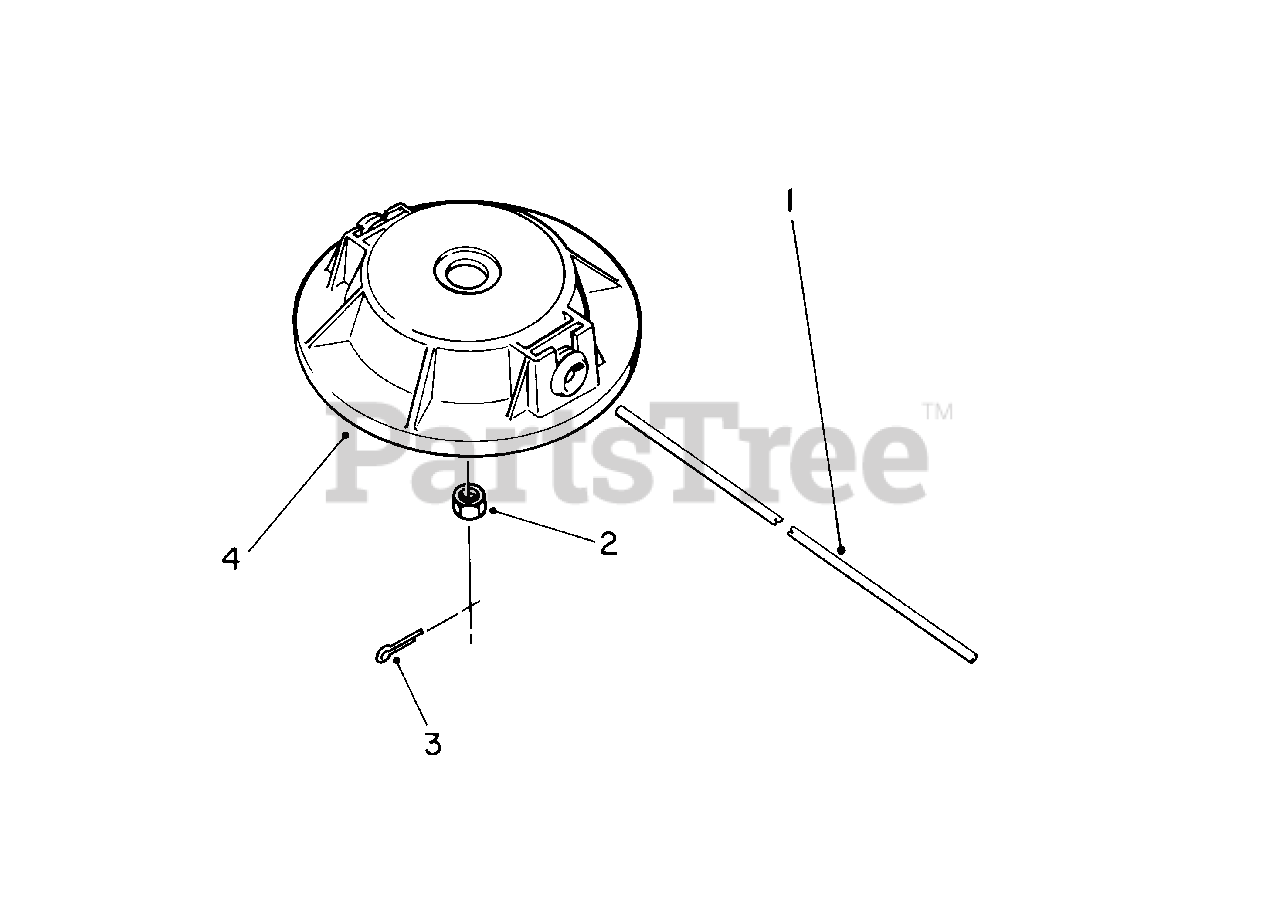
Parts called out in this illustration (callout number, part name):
1	Line-Cutting .105 Dia. (100 Pcs. Optional)
2	Nut Hex.
3	Pin-Cotter
4	Head Assembly
